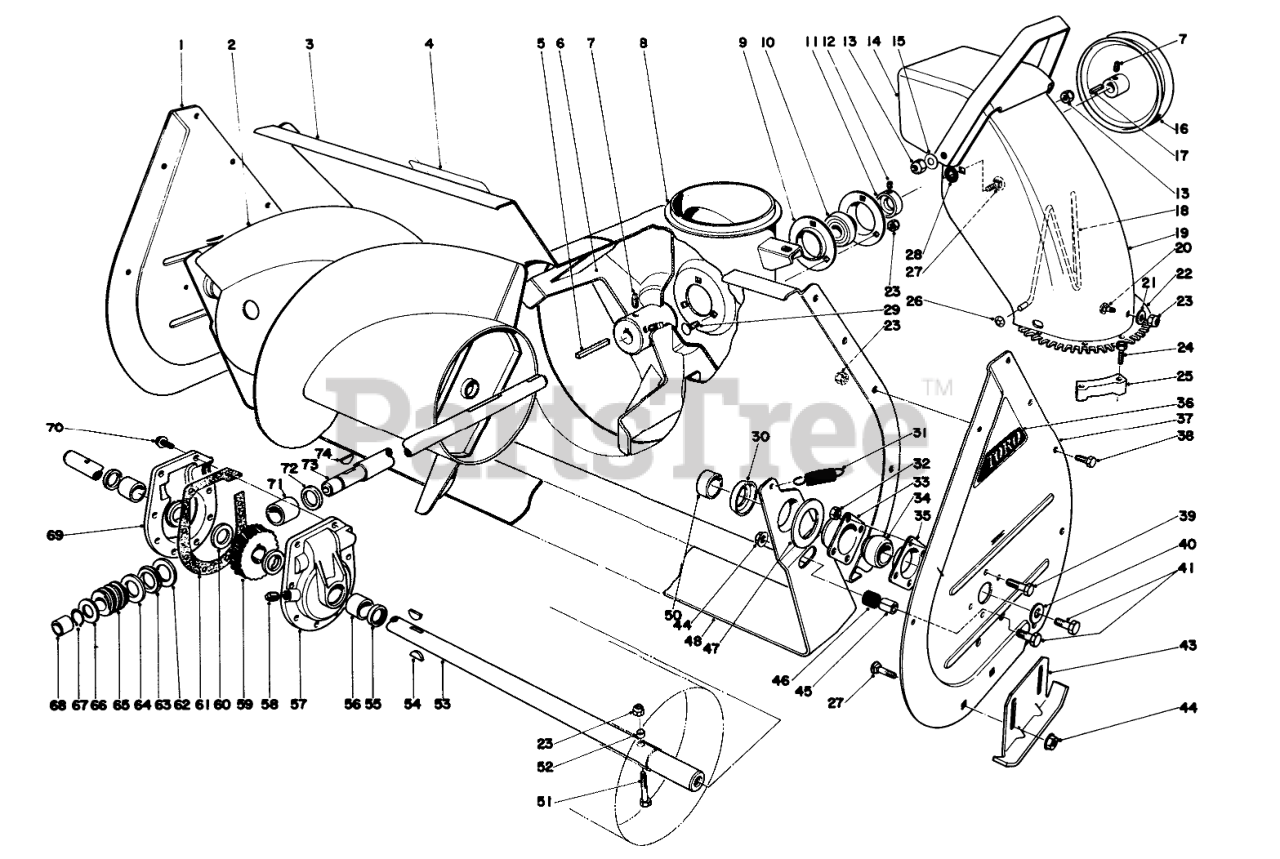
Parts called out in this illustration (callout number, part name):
1	RH AUGER SIDE PLT R
2	RH AUGER ASM - 32"
3	AUGER HSG WA 32" R
4	Decal-Warning
6	IMPELLER ASM
7	Set Screw
8	CHUTE RING
9	BRG FLANGE
10	BALL BRG W/COLLAR
11	EXT LOCKING COLLAR
12	SCREW-HSH
13	NUT-LOCK, CONE
14	Deflector
15	WASHER-BELLEVILLE
16	1/2 X 9.5 DIA PULLEY
17	SQUARE KEY
18	WIRE-CHUTE
19	Upper Chute
20	SCREW-CARR
21	WASHER-PLAIN
22	Screw
23	NUT-LOCK, NI
24	SCREW-SPECIAL
25	RETAINER-CHUTE
26	NUT-PUSH
27	SCREW-CARR
28	WASHER-RUBBER
29	BOLT-CARR
30	Positioner-Scraper
31	SPRING-TENSION
33	BEARING-FLANGE, FRONT
34	BEARING
35	BEARING-FLANGE, REAR
36	AUGER SIDE PLT DECAL
37	LH AUGER SIDE PLT R
38	SCREW-HH
39	SCREW-HH
40	WASHER
41	SCREW-HH
43	AUGER SKID WA R
44	NUT-HF
45	SCRAPER STOP SPACER
46	SCRAPER STOP CUSHION
47	SCRAPER BLADE SPACER
48	SCRAPER BLADE 32" R
50	AUGER SPACER
51	Auger Bolt
52	SPACER-HUB, AUGER
53	32 AUGER SHAFT
54	KEY-WOODRUFF
55	SEAL-OIL
56	BUSHING
57	Gear Case L.H. (Incl. Ref. #55-56)
58	PLUG-PIPE, SQH
59	GEAR-WORM, 27T
60	WASHER-THRUST
61	asket
62	WASHER-THRUST
63	BEARING-THRUST
64	THRUST-WASHER
66	WASHER-THRUST
67	Ring-Snap
68	BUSHING
69	Gear Case R.H. (Incl. Ref. #55-56)
70	SCREW-TAPTITE
71	BUSHING-SPECIAL
72	RING-QUAD
73	SHAFT-IMPELLER
74	KEY-WOODRUFF
